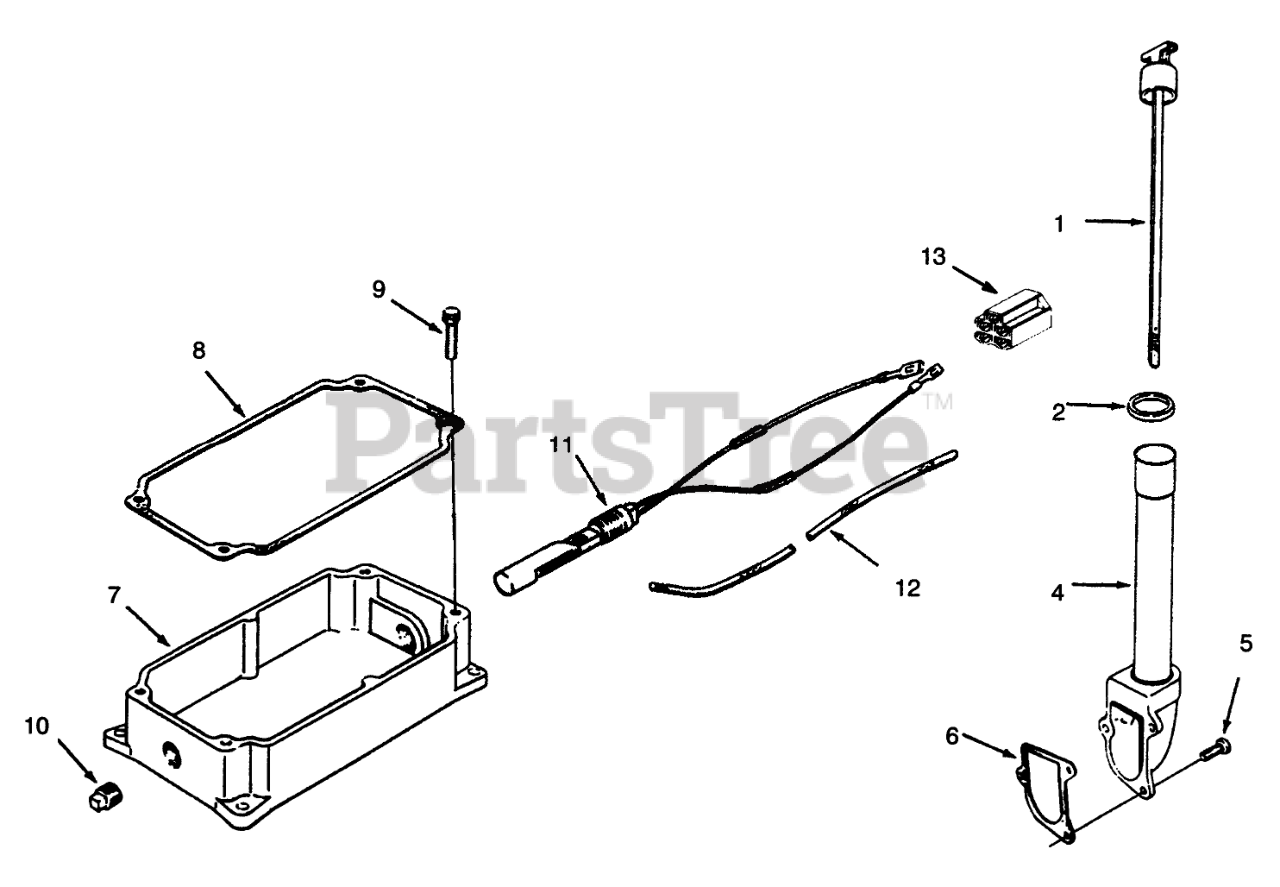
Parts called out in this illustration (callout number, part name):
1	Dipstick
2	0-Ring
4	Adapter-Oil Fill
5	Screw
6	Gasket
7	Oil Pan
8	Gasket
9	Screw
11	Kit-Float Switch (Incl. Ref. #12 & Decal)
12	Sleeve
13	Connector
